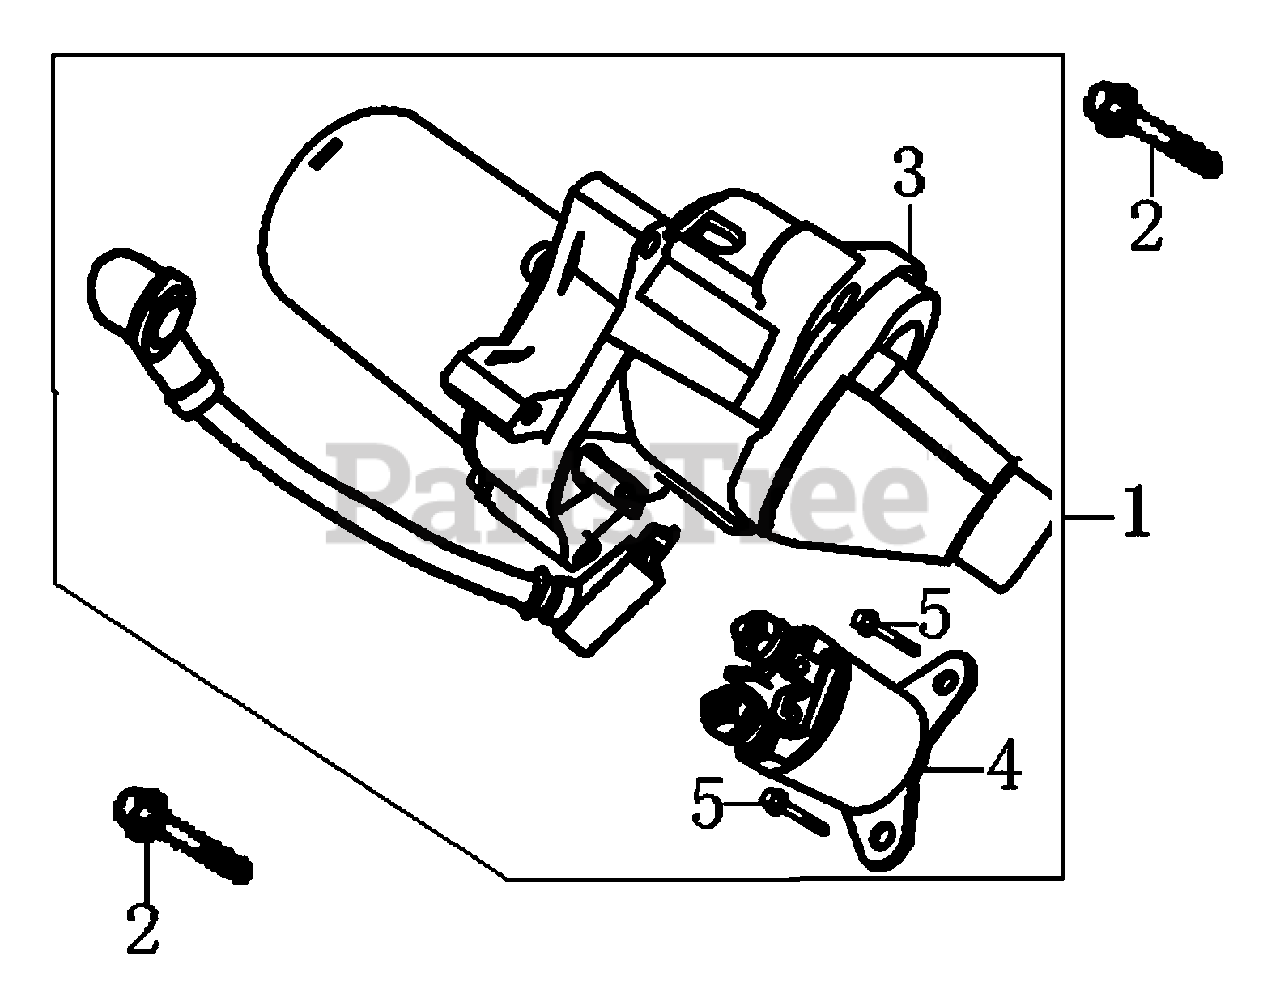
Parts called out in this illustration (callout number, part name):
1	MOTOR ASSY., STARTER
2	BOLT, FLANGE,
3	MOTOR, STARTER
4	CONTACTOR ASSY
5	BOLT, FLANGE,
